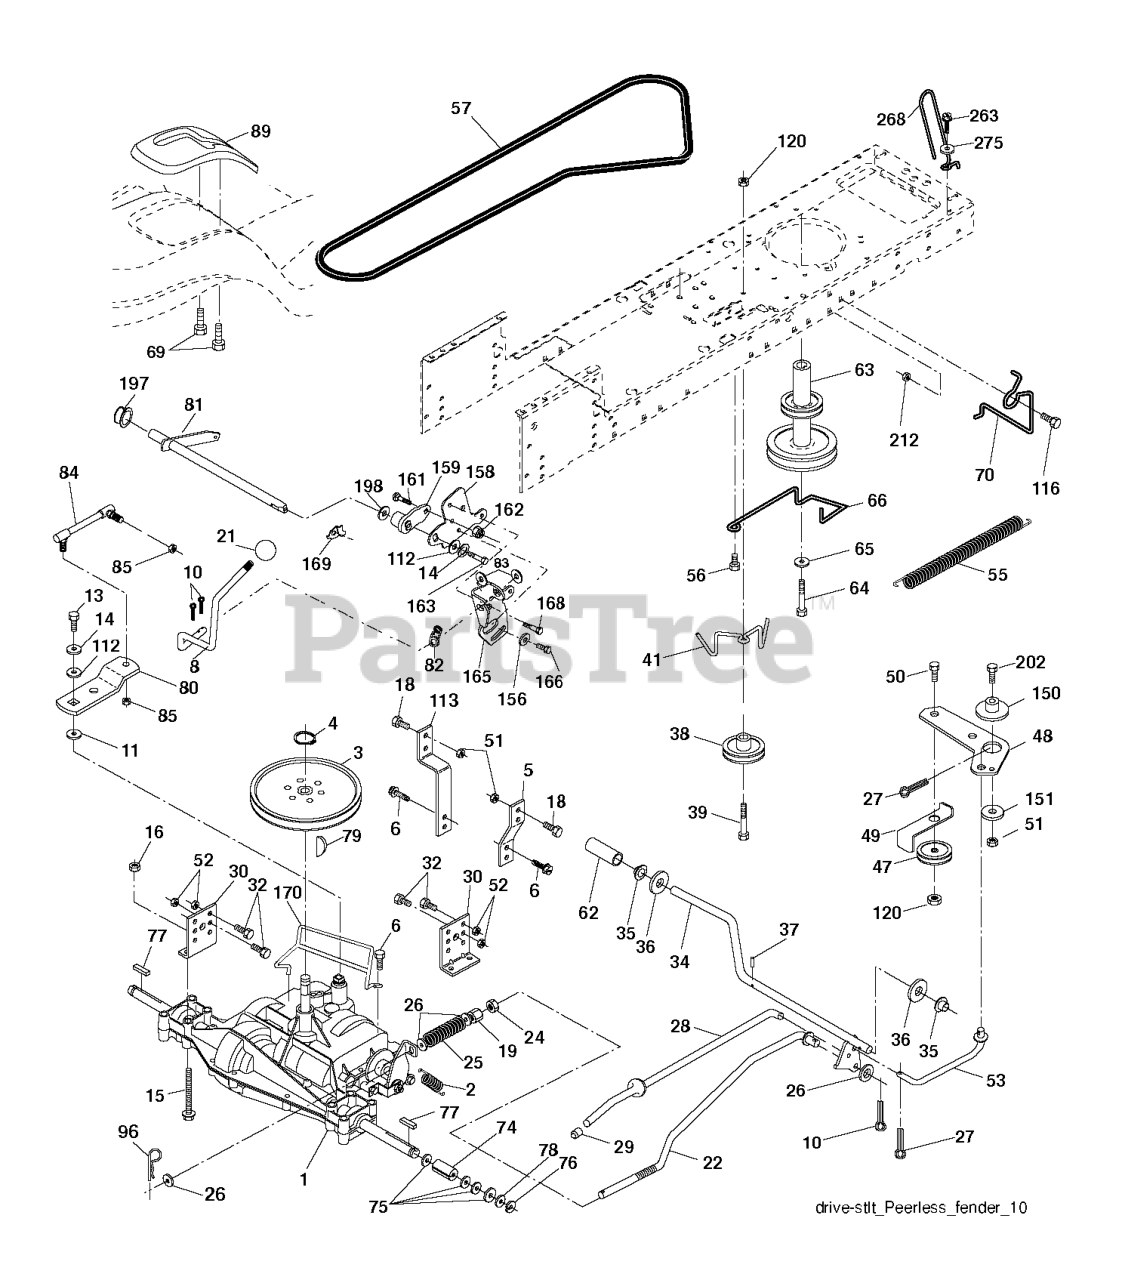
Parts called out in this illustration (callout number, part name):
2	SPRING,BRAKE RETURN
3	PULLEY TRANS
4	RETAINING RING LT
5	STRAP TORQUE
6	SCREW 5/16"
8	ROD SHIFT FENDER ADJUST LT
10	PIN COTTER
11	WASH-SHFT PLT LT
13	BOLT 1/4-28X3/4
14	LOCKWASHER
15	BOLT HEX 5/16-18 GR 5
16	NUT.71038.31-18.HEX.NYLOCK
19	NUT
21	KNOB T (1/2-HOLE)
24	NUT
25	SPRING ROD LT
26	WASHER
27	COTTER PIN
28	ROD, PARKING BRAKE
29	PLUNGER CAP
30	BRKT, MOUNT TRNSAXLE
32	BOLT
34	SHAFT, FOOT PEDAL
35	BEARING.NYLON
37	DRIVE PIN
38	PULLEY IDLER COMPOSITE
41	KEEPER, BELT IDLER
47	IDLER PULLEY
48	BELLCRANK, CLUTCH
49	RETAIN BELT
50	BOLT.3/8-16X1.50
52	LOCKNUT
53	LINK.CLUTCH.7.66.2005
55	SPRING, RETURN LT
56	SCREW.3/8-16
57	BELT, V GROUND DRIVE 95 25
62	PEDAL COVER T
63	ENGINE PULLEY
64	BOLT HEX 7/16-20X4-1/4"
65	LOCKWASHER
66	KEEPER BELT ENGINE
69	SCREW.HI-LO.CONSOLE
70	KEEPER BELT ENG
74	SPACER AXLE
77	SQUARE KEY
79	KEY STD (1373) DANA
81	SHAFT ASM CROSS TAPERED
82	SHIFT SPRING
83	WASHER
84	LINK.TRNSAXLE
85	NUT LOCK CENTER 1/4 -28 FNTHD
89	CONSOLE.SVC.SHIFT.LTST.5SP.BLK
96	RETAINER M
113	STRAP TORQUE LH LT
116	BOLT D
120	NUT LOCK FLG 3/8-16 UNC
150	SPACER, RETAINER
151	WASHER 12/32X2X10GA
156	WASHER.SRRTD.5/16
158	BRACKET
159	RB HUB.SHIFT
161	BOLT
162	NUT.CROWNLOCK.1/4
165	RP BRACKET
166	CAPSCREW.HXHD.FLG.5/16-18X.625
168	BOLT.SHOULDER.5/16-18X
169	PLATE.FASTENING.CROSS.SHAFT
170	KEEPER BELT T/A
197	NYLINER SNAP 5/8" ID
198	WASHER.NYL.7/8IDX.105"HYD CR
212	NUT
263	SCREW, 3/8-16X3/4
268	GUARD MUFFLER
275	WASHER
